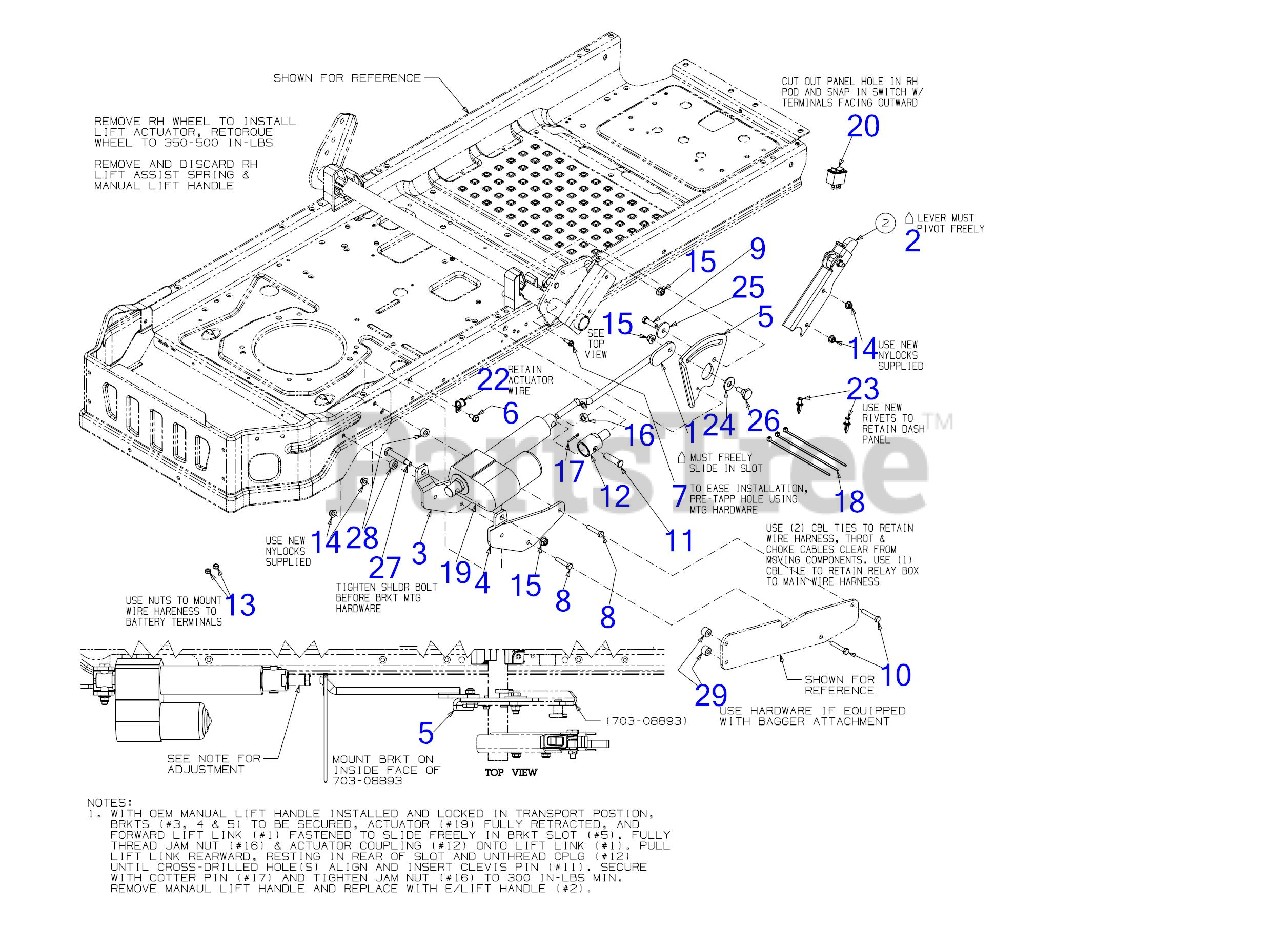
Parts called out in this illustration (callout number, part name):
1	ACTUATOR LIFT LINK
2	ELECTRIC LIFT HANDLE
2	LIFT LATCH
2	TORSION SPRING .75 OD x .4 LG (LH)
2	JAM LOCK NUT
2	SHOULDER SCREW .50
3	ACTUATOR MOUNTING BRACKET INNER
4	ACTUATOR MOUNTING BRACKET OUTER
6	SCREW 5/16-18 x .750
7	SCREW 1/4-20 x .750
8	SCREW 5/16-18 x 1.5 LG
9	SCREW 3/8-16 x 1.25 GR5
10	SCREW 5/16-18 x 1.75 GR5
11	CLEVIS PIN .50 x 1.59
12	ACTUATOR COUPLING
13	SEMS NUT 1/4-20
14	FLANGE LOCK NUT 5/16-18
16	HEX NUT
17	COTTER PIN-1/8 D
18	7" CABLE TIE
19	ACTUATOR LIFT
20	PLOW LIFT SWITCH
23	PLASTIC RIVET
24	FLAT WASHER
25	FLAT WASHER .390x1.500x.134
26	SHOULDER SCREW
27	SHOULDER SCREW .498 DIA x 2.045
